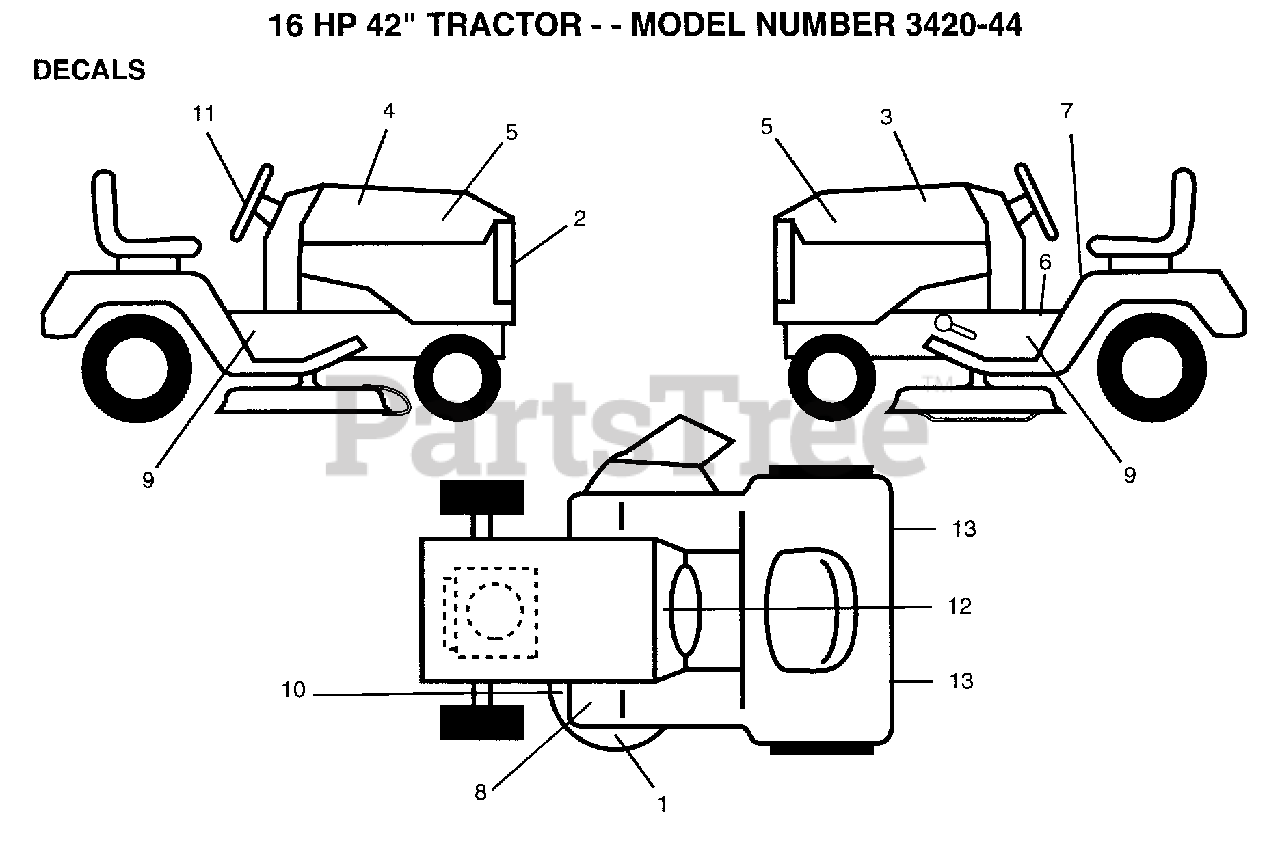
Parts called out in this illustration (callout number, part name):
2	GRILL DECAL
3	HOOD DECAL LH
5	NAMEPLATE LOGO
6	DECAL BRAK PARK
7	DECAL
9	DECAL CHASSIS
10	DECAL.V.BELT
12	DECAL.DASH.INST.
13	REFLECTOR-TAIL YT
